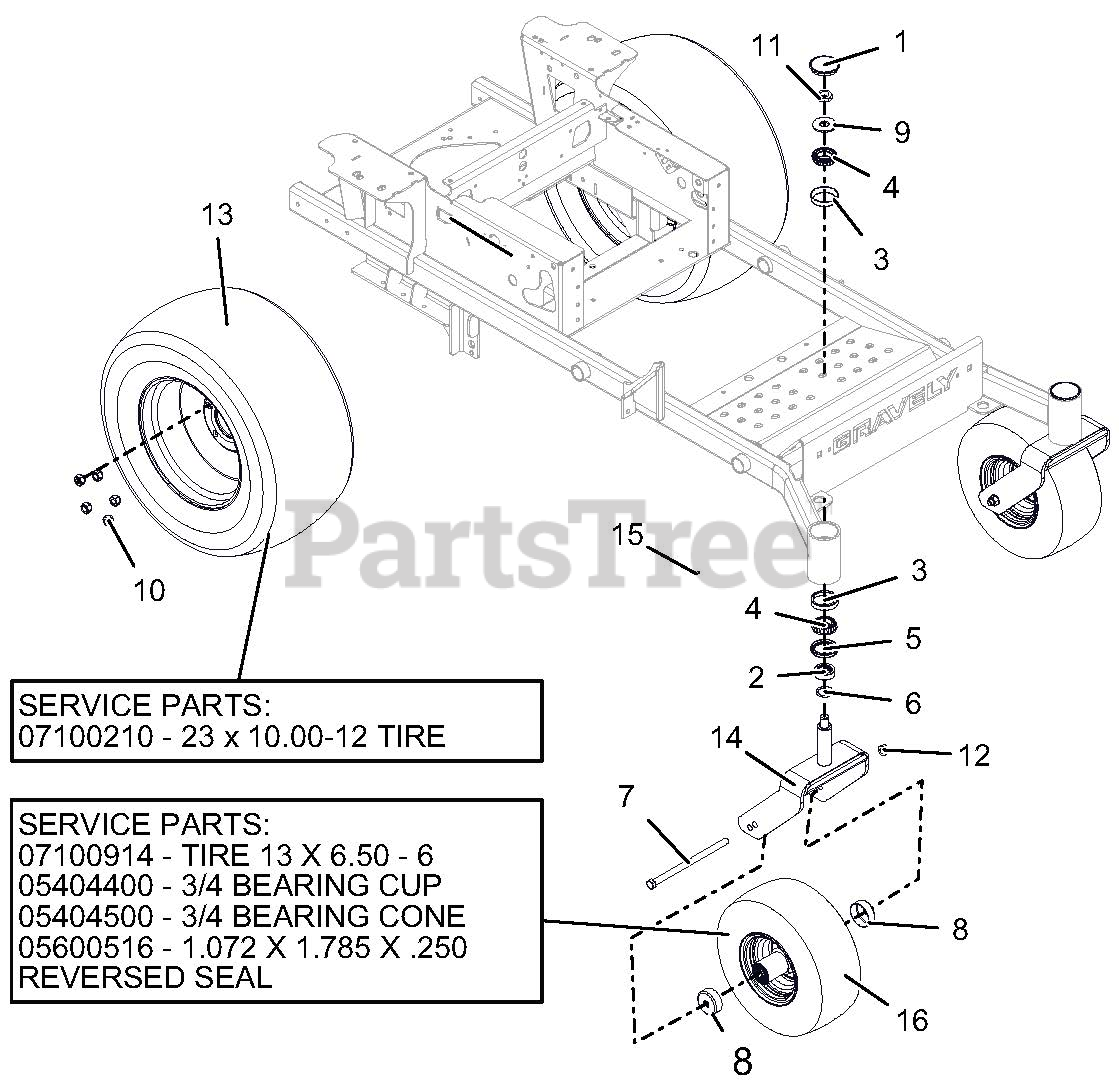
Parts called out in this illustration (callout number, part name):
1	CAP, DUST
2	SPCR, FRONT CASTER FORK
3	BRG, CUP 2.328 X .465
4	BRG, CONE 1.250 X .660
5	SEAL, OIL 1.75 X 2.332 X .312
6	O-RING, .139 W X 1.234 ID
7	BLT-HEX .50-13X9.00 GR5 YWZC
8	SHIELD, WHEEL BEARING
9	WSHR-FL-STL.812X2.00X.148YWZC
10	NUT, LUG .500-13
11	NUT, JAM CTRLK .75-16 YWZC
12	NUT, LK-TOP-FLG .50-13 YWZC
13	ASSM TIREWHEEL, 23X10-12
13	23 X 10.00-12 TIRE
14	WMT, CASTER FORK - RED
15	FITTING, .250-28 FLUSH MOUNT GREASE
16	TIRE/WHEEL, 13 X 6.50-6 SMOOTH
16	TIRE 13 X 6.50-6
16	3/4 BEARING CUP
16	3/4 BEARING CONE
16	1.072 X 1.785 X .250 REVERSED SEAL
